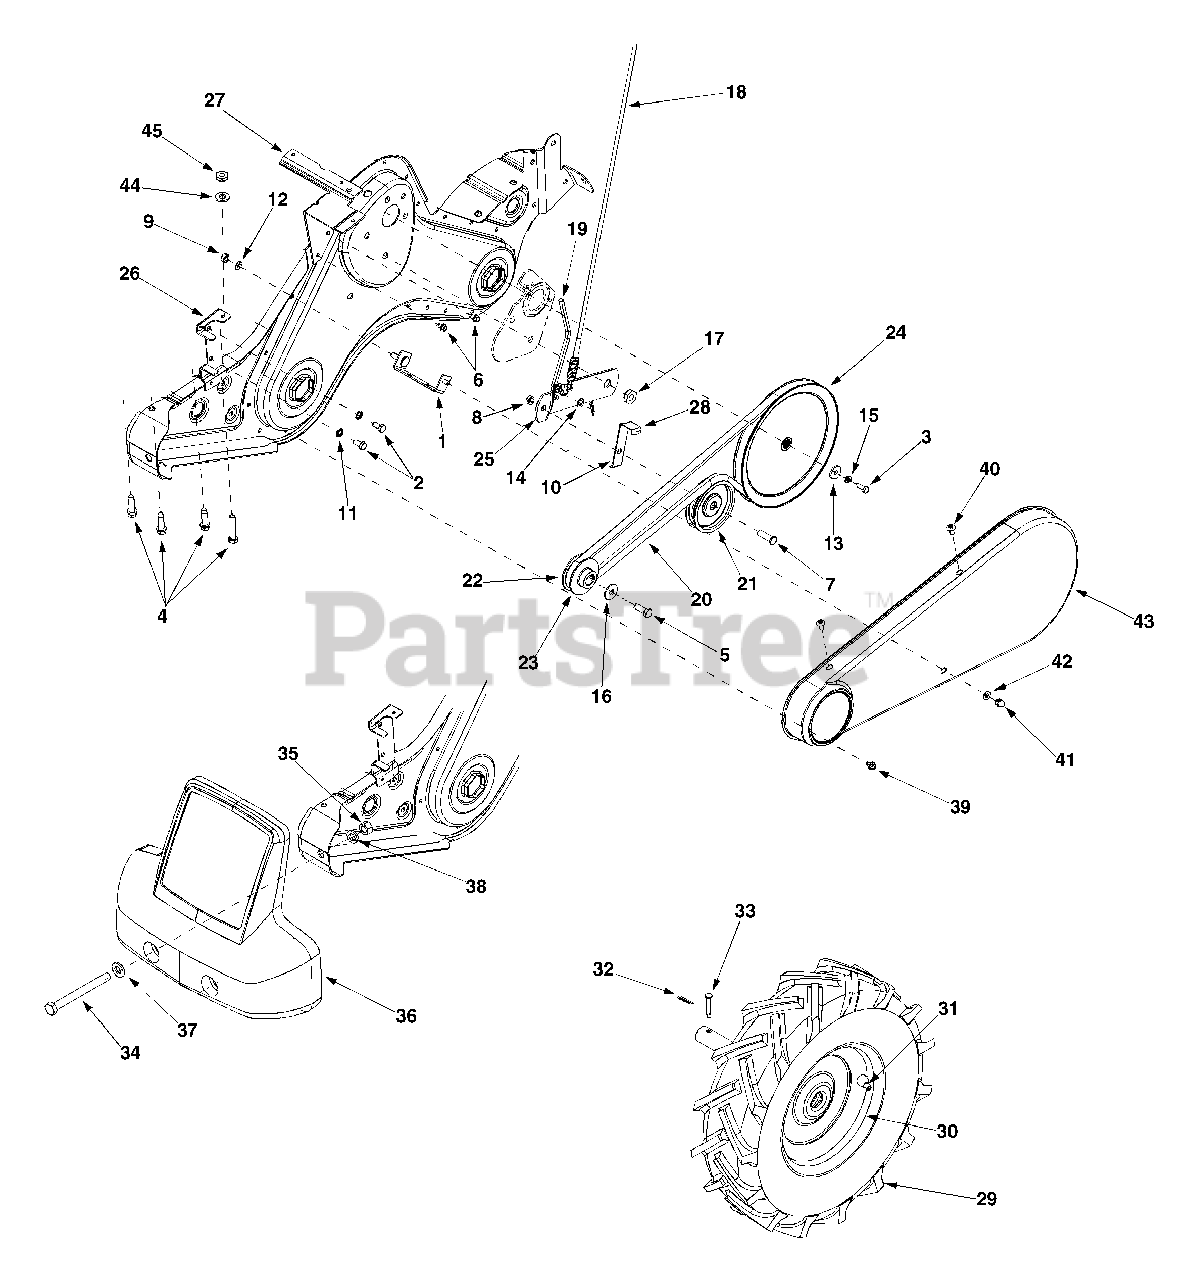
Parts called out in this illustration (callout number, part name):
1	Belt Cover Bracket Ass'y
2	Hex Bolt 5/16-24 x .62"
3	Hex Bolt 1/4-28 x .75"
4	Hex Washer Screw 3/8-16 x 1.25"
5	Hex Bolt 3/8-24 x 1.0
6	Hex Washer Screw
7	Hex Cap Screw 3/8-16 x 1.25
8	Lock Jam Nut 3/8-16
9	Hex Nut 5/16-18
10	Internal Cotter Pin
11	Hairpin Clip
12	Lock Washer 5/16"
13	Flat Washer .25 ID x .93 OD
14	Spring Washer .317 ID x .625 OD
15	Lock Washer 1/4" ID
16	Bell Washer .396 ID x 1.14 OD
17	Shoulder Nut 7/16-20
18	Clutch Cable
19	Idler Pulley Rod
20	V-Belt
21	Flat Idler w/Flange 3.75 OD
22	Outer Engine Pulley Half
23	Inner Engine Pulley Half
24	Input Pulley
25	Idler Bracket
26	Belt Keeper Bracket
27	Shift Cover Bracket
28	Idler Belt Keeper
29	Wheel Assembly RH 16.0 x 4.6
29	Wheel Assembly LH 16.0 x 4.6
29	Tire Only 16.2 x 4.6
32	Clevis Pin
33	Internal Cotter Pin
34	Hex Bolt 1/2-13 x 5.0
35	Hex Nut 1/2-13
36	Counterweight
37	Flat Washer
38	Lock Washer 1/2
39	Hex Screw 1/4-20 x .375
40	Screw 1/4-14 x .625
41	Lock Nut
42	Flat Washer .271 ID x .630 OD
44	Bell Washer .340 ID x .872 OD
45	Hex Nut 5/16-18
